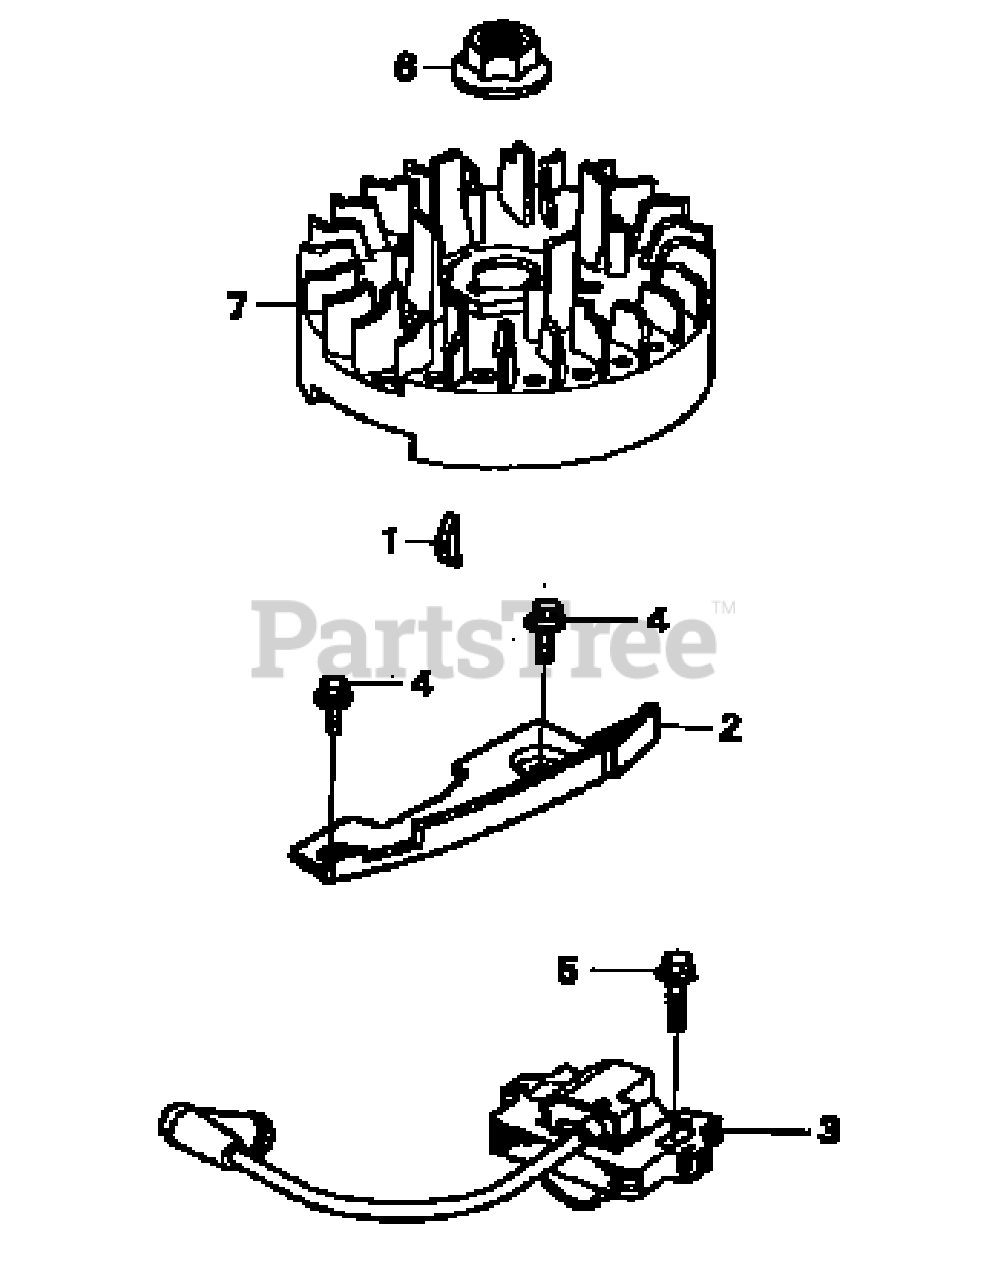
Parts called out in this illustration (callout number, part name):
1	Special Woodruff Key
2	Side Plate
3	Ignition Coil Assy.
4	Flange Bolt (6x12)
5	Flange Bolt (6x20)
6	Special Nut (14mm)
